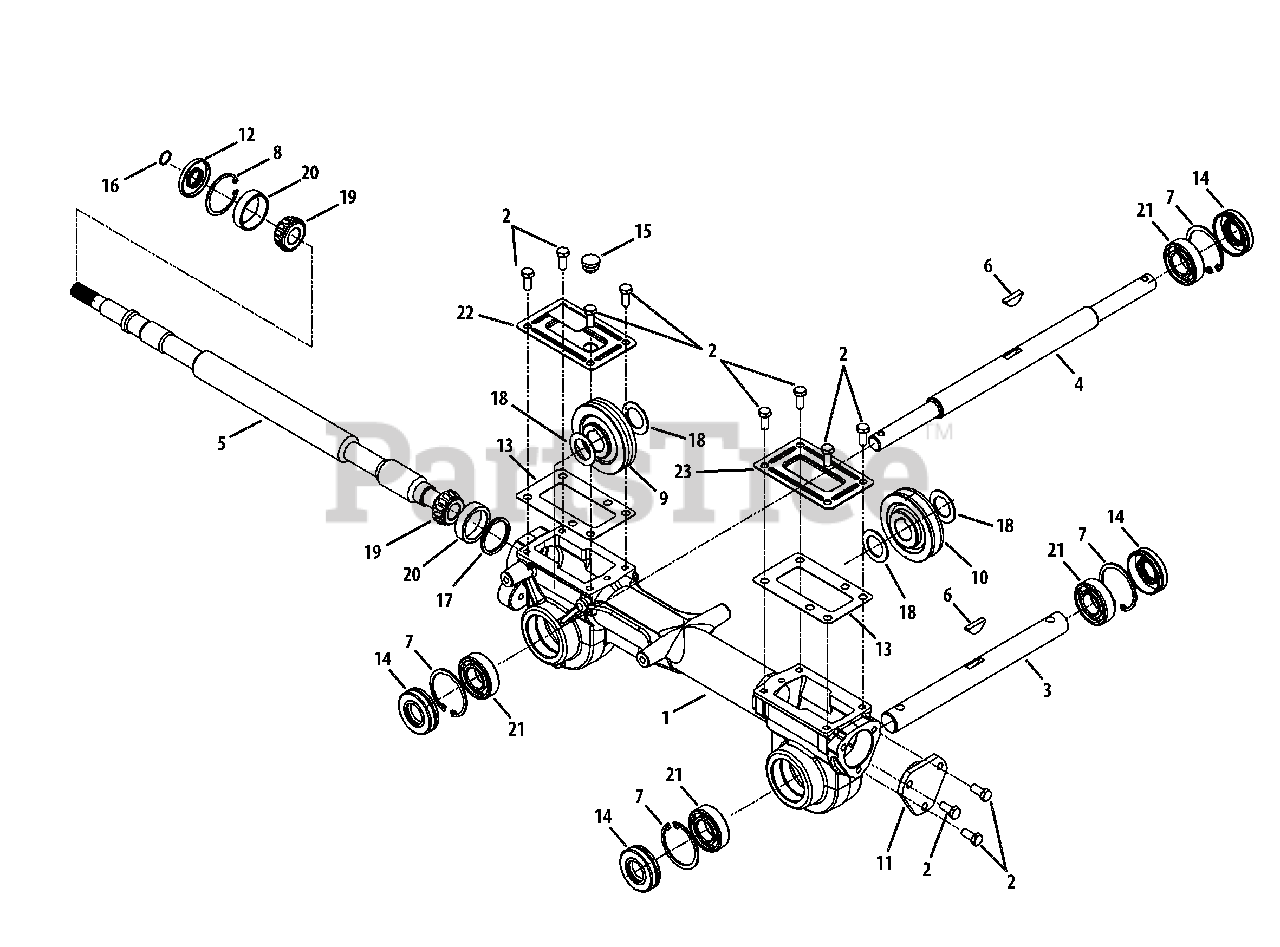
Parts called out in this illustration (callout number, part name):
1	Housing, Transmission
2	Hex Screw, 5/16-18, .75, Gr5
3	Shaft, Tiller
4	Shaft, Wheel
5	Shaft, Worm
6	Key, Hi Pro .25 x 1.062
7	Retaining Ring
8	Retaining Ring, Int
9	Worm Gear, 61t, RH
10	Worm Gear, 30t, LH
11	Bearing Cover
12	Seal, Oil, .750 Shaft x 1.783 Bore
13	Gasket, Gear Housing
14	Seal, Oil, 1.00 Shaft x 2.00 Bore
15	Rubber Plug, Oil
16	Wire Ring
17	Washer, Flat, 1.50 x 1.75 x .062
17	Washer, Flat, 1.50 x 1.75 x .005
17	Washer, Flat, 1.50 x 1.75 x .03
17	Washer, Flat, 1.50 x 1.75 x .010
18	Washer, Flat, 1.010 x 1.56 x .060
19	Cone Bearing
20	Bearing Cup
21	Ball Bearing
22	Cover, Transmission
23	Cover, Transmission
